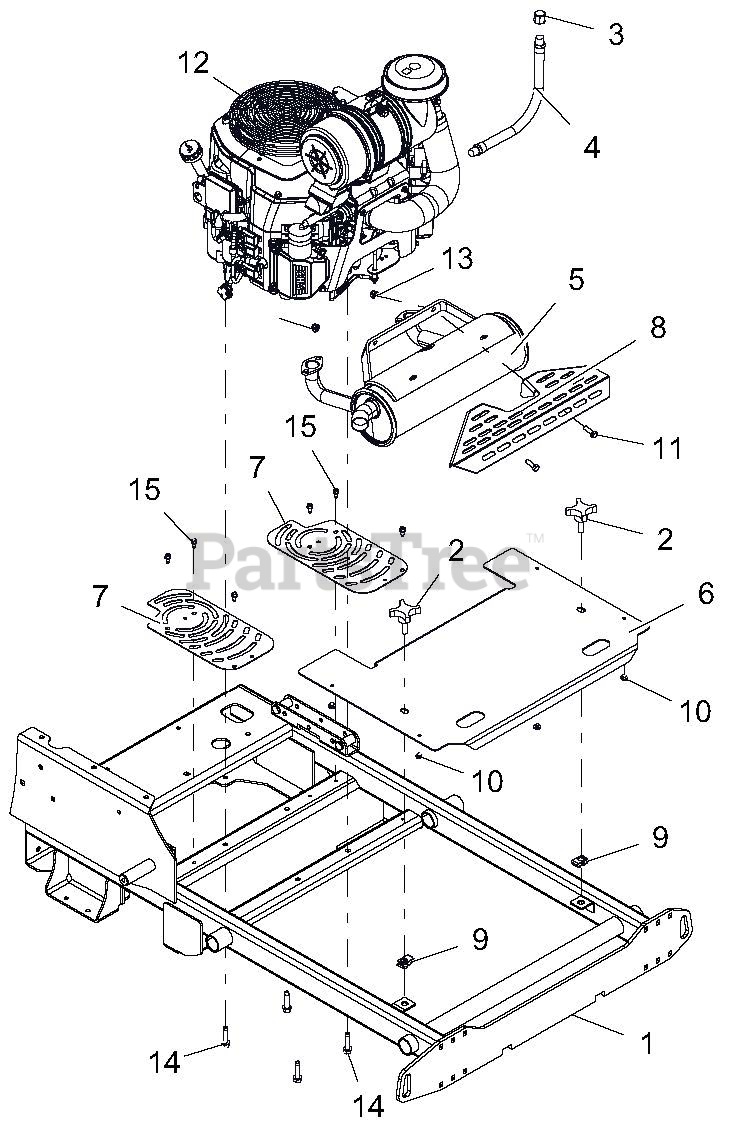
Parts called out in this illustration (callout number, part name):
1	WLDMT, FRAME PROSTANCE
2	KNOB, 3/8 X 1.25 - 4 PRONG
3	PIPE, CAP 3/8 NPT FEMALE
4	HOSE, HYD .38-11-OK M6N0-M6N0
5	MFLR, KOHLER
6	SHIELD, FRONT PRO-STANCE
7	GUARD, FAN
8	GUARD, HEAT SHIELD
9	NUT, RTNR .375-16X.37
10	BUMPER GROMMET .125 X .25 REV
11	BLT-HEX .31-18X1.00 GR5 YWZC
12	ENGINE, KOHLER EFI ECV740
13	NUT-LK-NYL-FLG .31-18 YWZC
14	SCR-TAP .38-16X1.50 HWH TR YZ
15	SCR-TAP .25-20X.50 HWH TR YWZ
